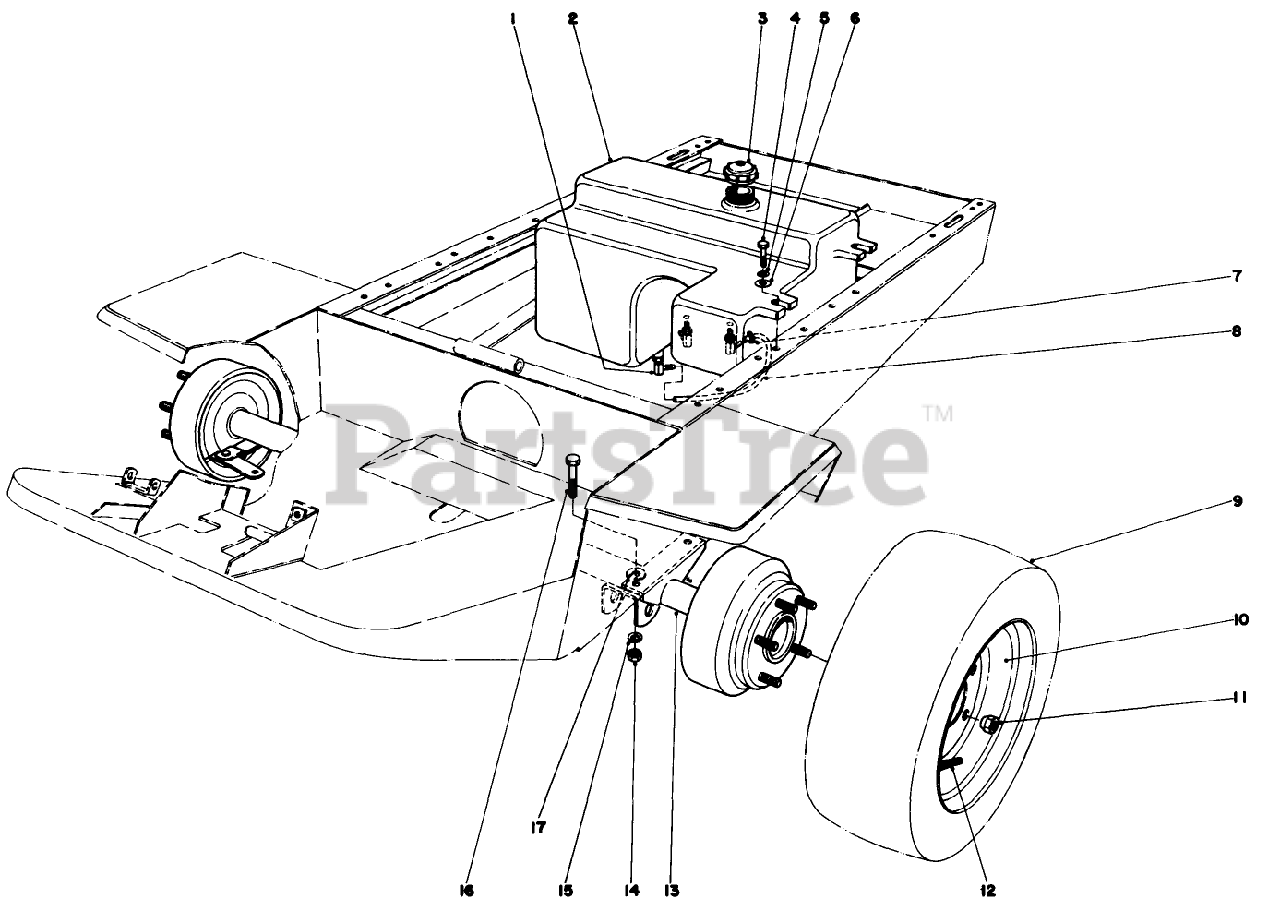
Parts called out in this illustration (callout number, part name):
1	FITTING-ELBOW, 90 DEG
2	Gas Tank
3	GAS CAP
4	SCREW-HH
5	WASHER-LOCK
6	WASHER-FLAT
7	CLAMP-HOSE
8	HOSE-FUEL
9	Tire
10	WHEEL ASM
11	NUT-WHEEL
12	VALVE STEM AND CAP ASM
14	NUT-HEX
15	WASHER-LOCK
16	Capscrew
17	SPECIAL WASHER
